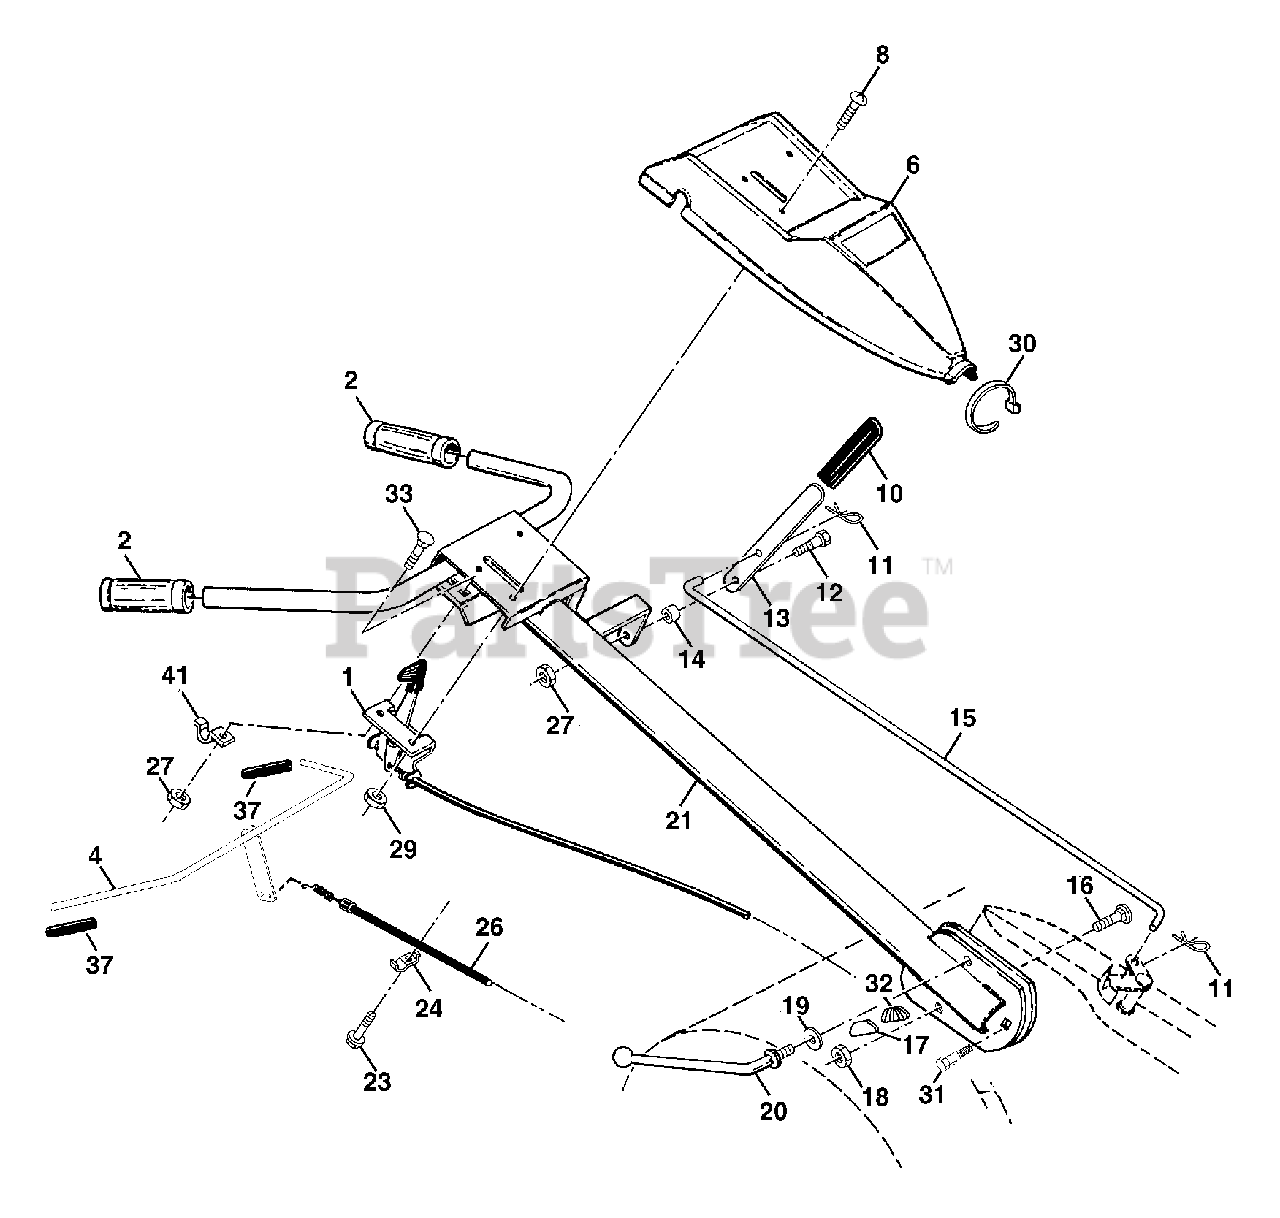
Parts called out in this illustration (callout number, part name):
1	Control, Throttle
2	Grip, Handle
4	Bar Assembly, Control
6	Panel, Control
8	Screw, Pan Hd. #10-24 UNC
10	Grip, Handle
11	Clip, Hairpin
12	Bolt, Shoulder
13	Handle, Shift
14	Grommet, Rubber
15	Rod, Shift
16	Bolt, Carriage 3/8-16 x 1
17	Lock, Handle
18	Nut Crownlock 3/8-16 UNC
19	Washer 13/32 x 1 x 11 Ga.
20	Lever, Lock, Handle
23	Screw Hex Wsh Slt #10-24 x .50
24	Clip
26	Cable, Clutch
27	Nut, Hex 1/4-20 UNC
29	Nut, Keps #10-24 UNC
30	Tie Cable
31	Bolt, Pivot
32	Lock Handle
33	Bolt, Carriage 1/4-20 UNC x 1/2
37	Grip, Bar, Control
41	Clamp, Bar, Control
